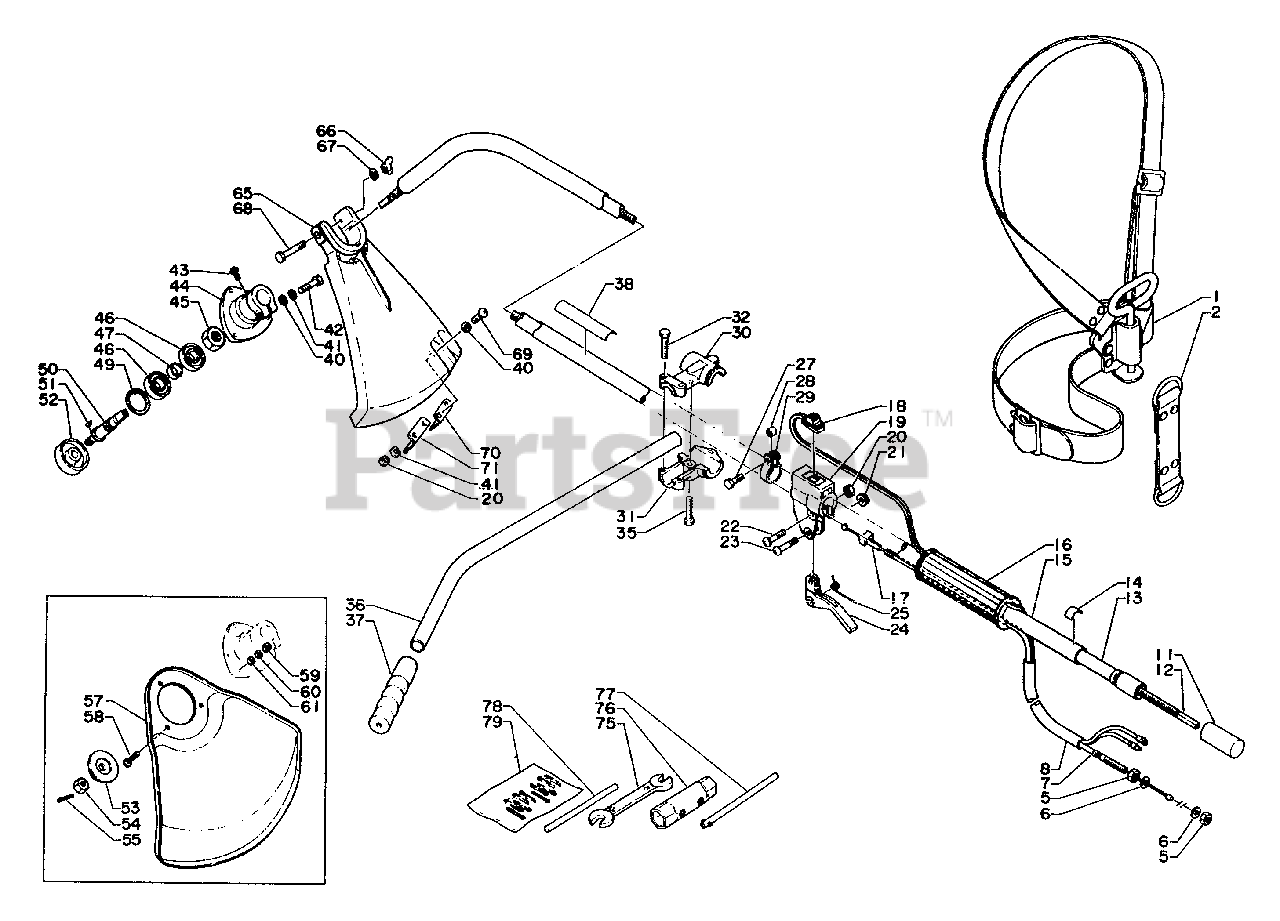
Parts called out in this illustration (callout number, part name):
1	SHOULDER STRAP ASSY
2	STRAP
6	WASHER 6.5×11.5×0.8
7	CABLE, THROTTLE
8	TUBE
11	CAP
12	DRIVESHAFT - FLEXIBLE
13	LINER
14	LABEL - ALIGNMENT
15	PIPE, MAIN
16	GRIP, HANDLE
17	GUIDE, CABLE
18	IGNITION SWITCH ASSY
19	BRACKET, THROTTLE
20	NUT M5
21	LOCKNUT - 5
22	SCREW - 5×28
24	TRIGGER, THROTTLE
25	SPRING, THROTTLE
27	BOLT 5×18
28	SPACER, GUARD
30	BRACKET
31	BRACKET
32	BOLT - 5×25
35	BOLT 5×28
36	HANDLE
38	LABEL - CAUTION
40	WASHER, FLAT 5.5×10×0.8
41	WASHER, SPRING 5
42	BOLT - 5×25
43	SCREW 4×10
44	CASE, BEARING
45	NUT - 12 -- LEFT HAND
46	BEARING, BALL 6001 DDU
49	RING, SNAP 28
50	GEAR, SHAFT
52	PLATE, ADAPTER - UPPER
53	PLATE, ADAPTER - LOWER
55	PIN, SPLIT
57	SHIELD ASS'Y (STEEL)
58	SCREW 4×18
60	WASHER, SPRING 4 MM
61	WASHER 4 MM
65	SHIELD ASS'Y (PLASTIC)
66	NUT, WING 6
68	BOLT - 6×50
69	SCREW 5×14
70	KNIFE, TRIMMER LINE
75	SPANNER 8×10
76	WRENCH 17×19
77	ROD, HANDLE
78	TOOL, LOCKING 5×120 MM
79	PIN, COTTER 2×22 (PKG. OF 10)
